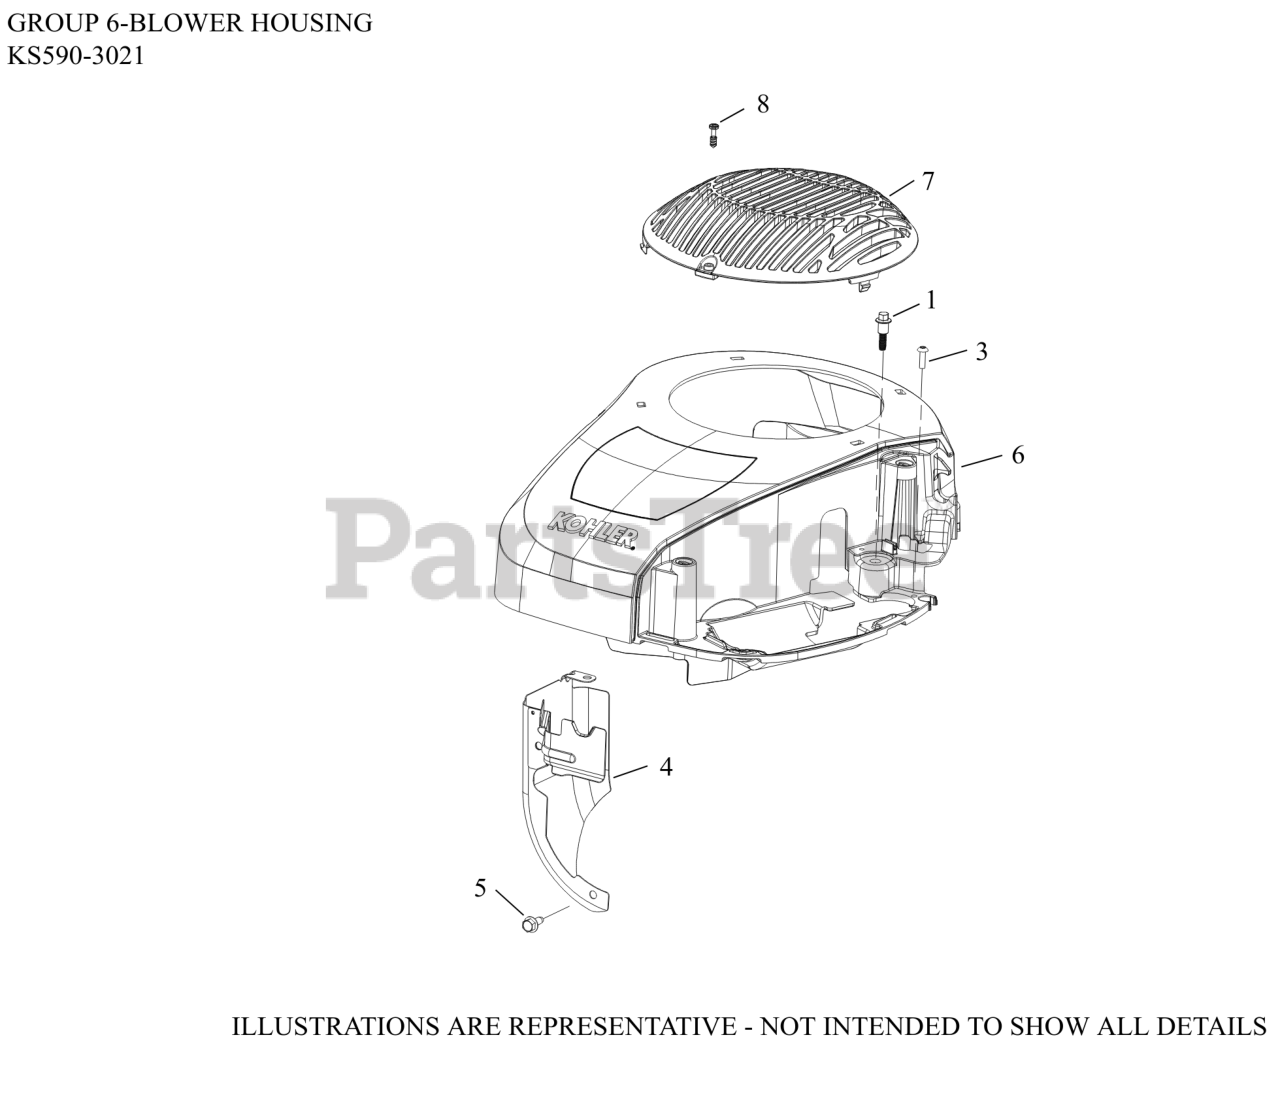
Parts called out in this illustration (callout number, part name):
1	SCREW, SHD THD FRM M6X1X26
3	SCREW, HI-LOW
4	BAFFLE, BARREL ASSY
5	SCREW, THREAD FORMING
6	KIT, BLOWER HOUSING-USE 22 027 05-S
7	GUARD, FIXED
8	SCREW, M5-2.42 (PT) THREAD
